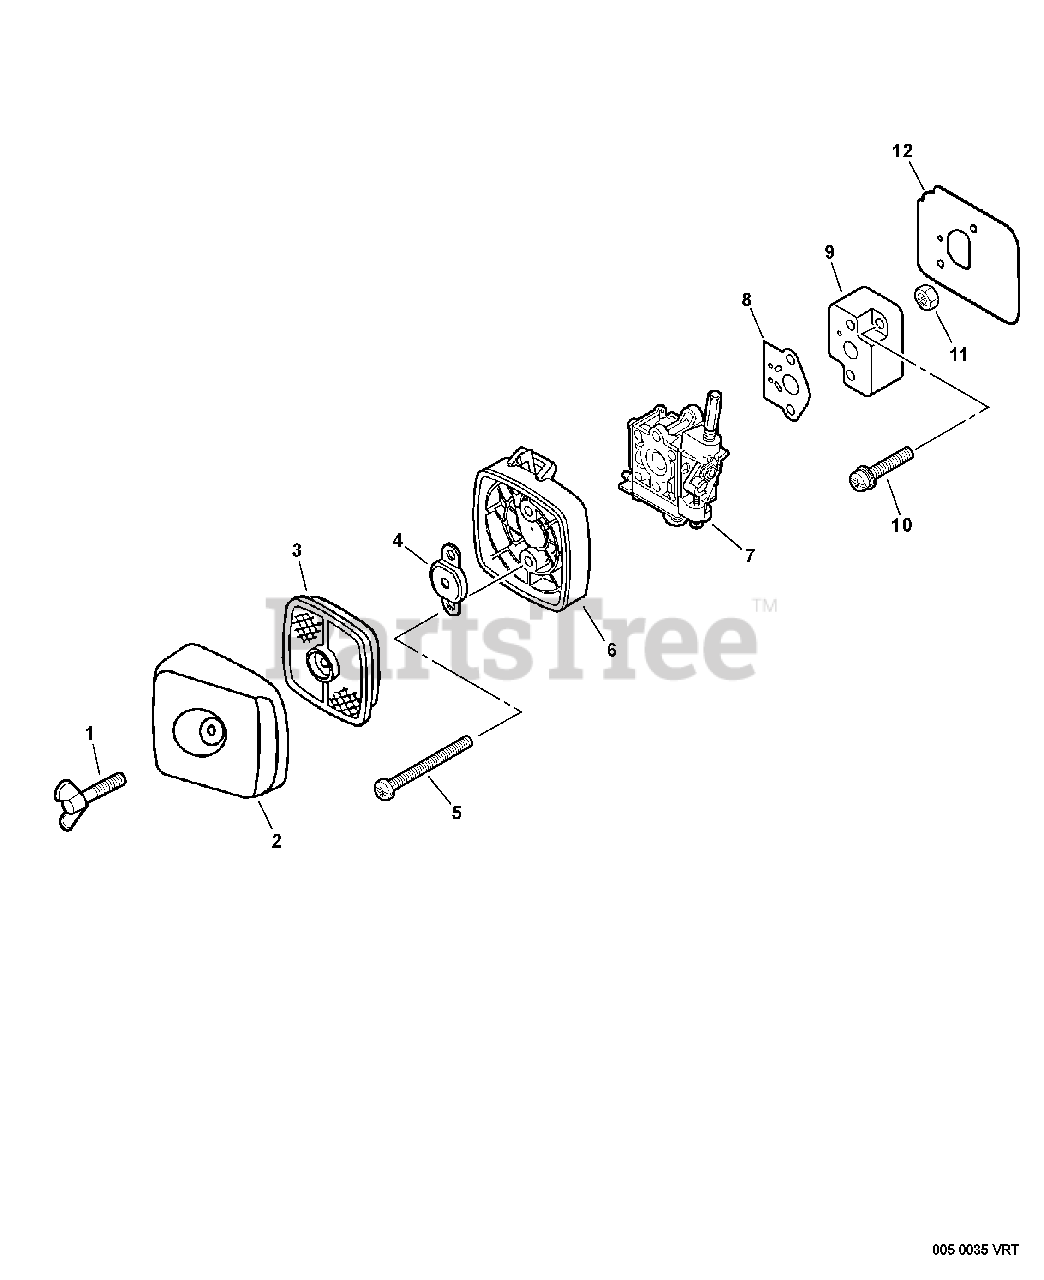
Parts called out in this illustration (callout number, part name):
1	THUMBSCREW
2	COVER, AIR FILTER - GRAY
3	FILTER, AIR - SINGLE LAYER
4	PLATE, PREVENT
5	SCREW - 5X65
6	CASE, AIR FILTER - GRAY
7	CARBURETOR
8	GASKET, INTAKE
9	INSULATOR, INTAKE
10	SCREW - 5X20
12	SHIELD, INTAKE
